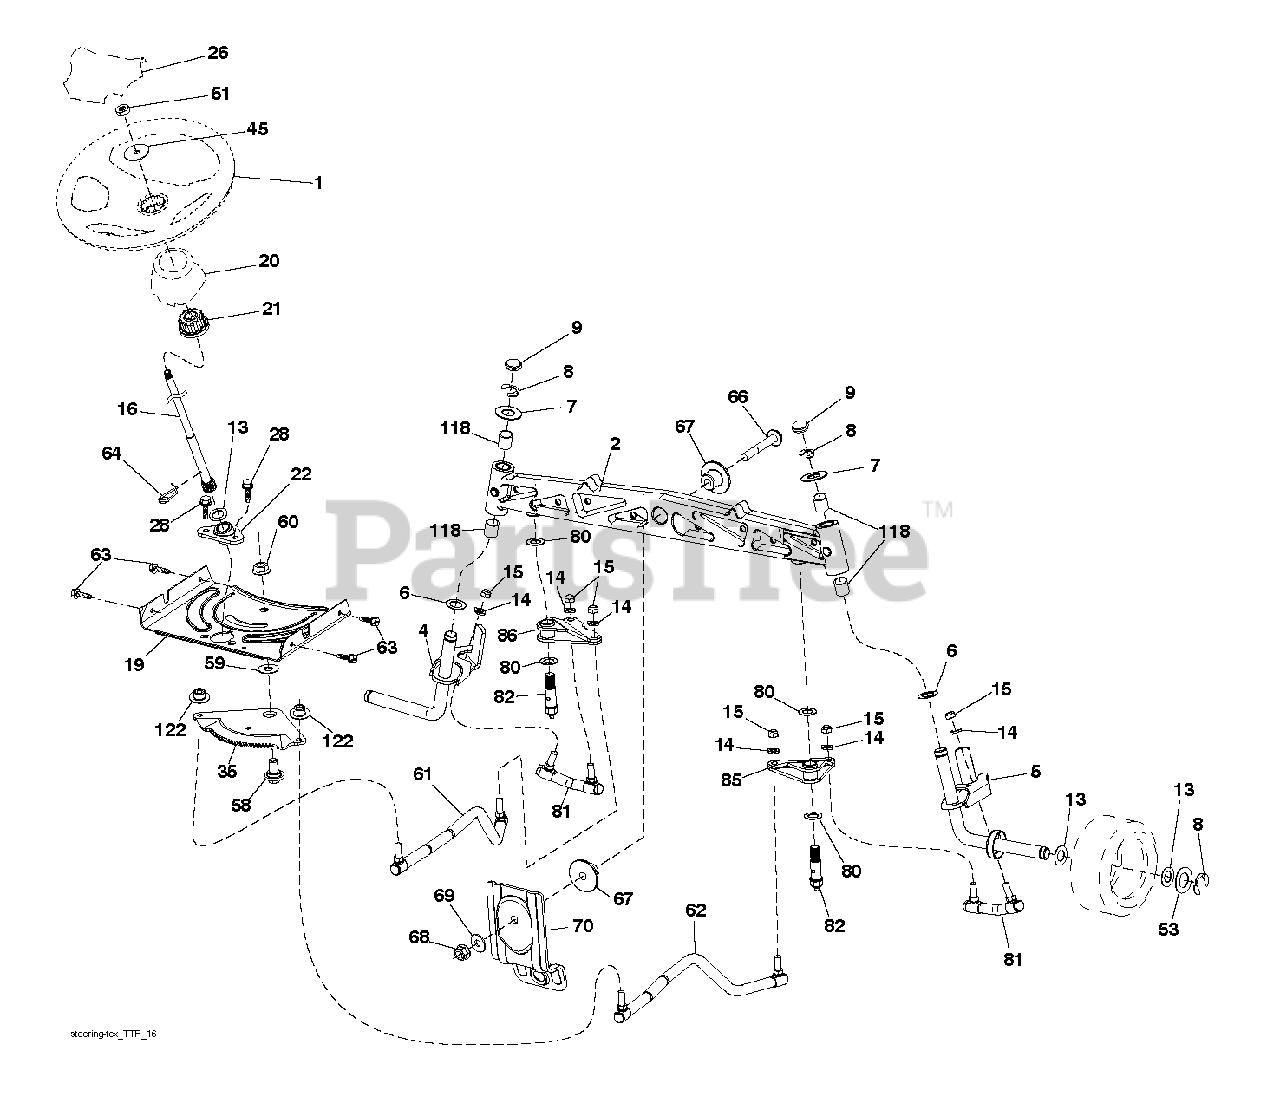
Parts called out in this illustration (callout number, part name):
1	WHEEL.STEERING.STDSRR.BLK/OV
2	RP SUBASM.AXLE.CAST.N
4	Spindle Weldment, LH.15.Nztr
5	Spindle Weldment, RH.15.Nztr
14	WASHER, LOCK 3/8
15	NUT CROWNLOCK 3/8-24
16	Steering Shaft Service Kit
19	PLATE.STEER.DDL.NLT/NG
20	BOOT.STRNG.PREDATOR.YT/GT.428
21	STEERING.WHEEL.ADAPTER
22	BUSHING.ASM.STEERING.A
26	CAP.WHL.STRNG.STDSRRD.SRS.BLK
28	SCREW, 3/8-16X3/4
35	NZTR Sector Gear, Tex
45	WASHER 9/16"ID, 2 3/8"OD
51	NUT.HEX.1/2-20
53	WASHER.HARDENED
58	BOLT.SHOULDER.SECTOR.P
59	WASHER.THURST.SECTOR.S
60	NUT FLANGE LOCK 5/8-11
61	LINK SUBASM.LINK.DRAG
62	Subassembly Link Drag, RH Nztr
63	SCREW
64	RETAINER.CLIP.SPRING.S
66	BOLT HEX FGHD 7/16-14 X 3 SERR
67	BUSHING.PM.FRONT AXLE
68	NUT.LOCK.FLANGE.7/16
69	WASHER.1.5X.505X.118
70	BRKT.DECK.SUSPENSION.F
80	THRUST WASHER
81	Subassembly Link Cross, RH Nztr
85	Subassembly Pivot, RH Nztr
86	Pivot Subassembly, LH.Nztr
118	NUT.HEX.1/2-20
122	CAP.GEAR.SECTOR.TEX
